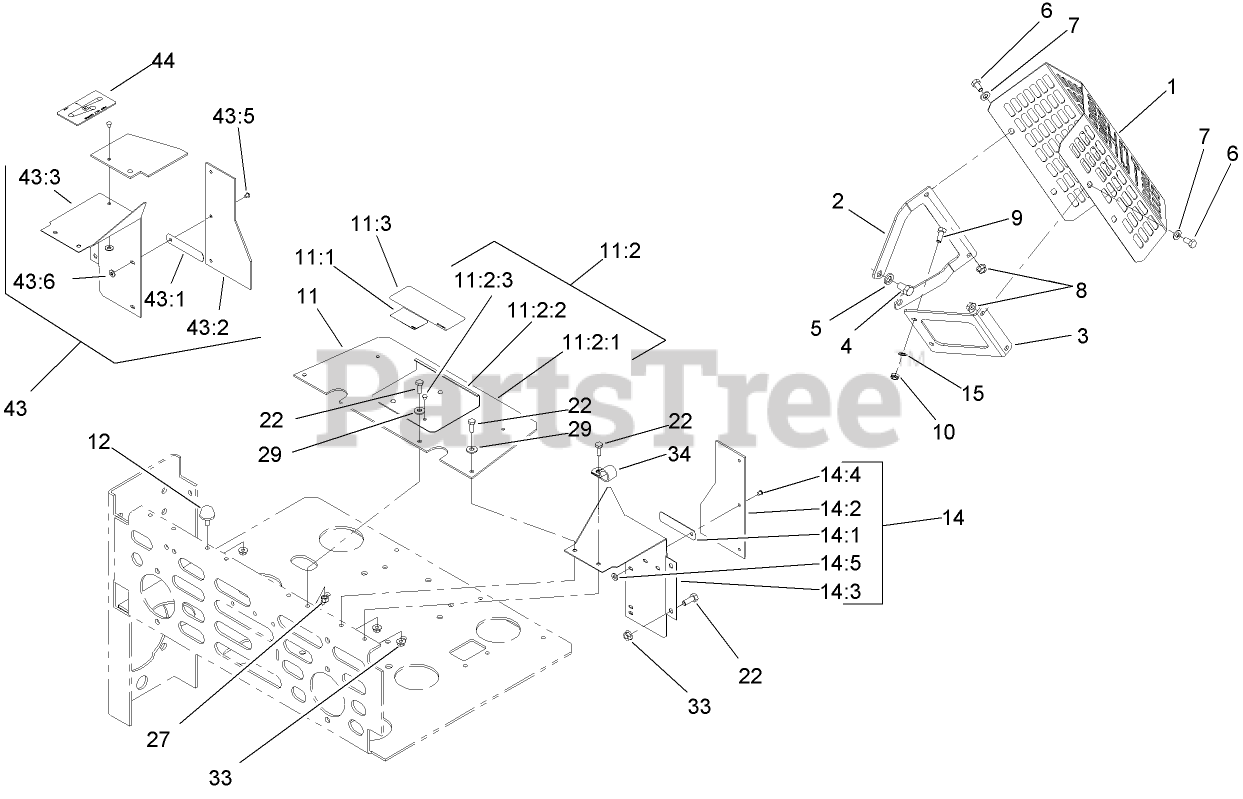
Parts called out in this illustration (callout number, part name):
1	GUARD-MUFFLER
2	BRACKET-MOUNT, MUFFLER
3	BRACKET-SUPPORT, MUFFLER
4	SCREW-HH
5	WASHER-LOCK
6	SCREW-HH
7	WASHER-PLAIN
8	NUT-HF
9	SCREW-HHF
10	NUT-HF
11	SHIELD ASM
11:1	DECAL-IMPORTANT
11:2	Drive Cover ASM
11:2:1	SHIELD-ENGINE
11:2:2	PLATE-COVER, DRIVE
11:2:3	RIVET-POP
11:3	DECAL-DEVICES, ROTATING
12	BUMPER-RUBBER
14	LH Extended Shield ASM
14:1	CLIP-BAFFLE, REAR
14:2	SHIELD
14:3	BAFFLE-ENGINE SHIELD, LH
14:4	RIVET-POP
14:5	WASHER-FLAT
15	WASHER-LOCK, SPRING
22	SCREW-HH
27	NUT-LOCK, NI
29	WASHER-FLAT
33	NUT-HF
34	CLIP-LOOM
43	RH Extended Shield ASM
43:1	CLIP-BAFFLE, REAR
43:2	SHIELD
43:3	SHIELD-RH
43:5	RIVET-POP
43:6	WASHER-FLAT
44	DECAL-ROUTING, BELT
